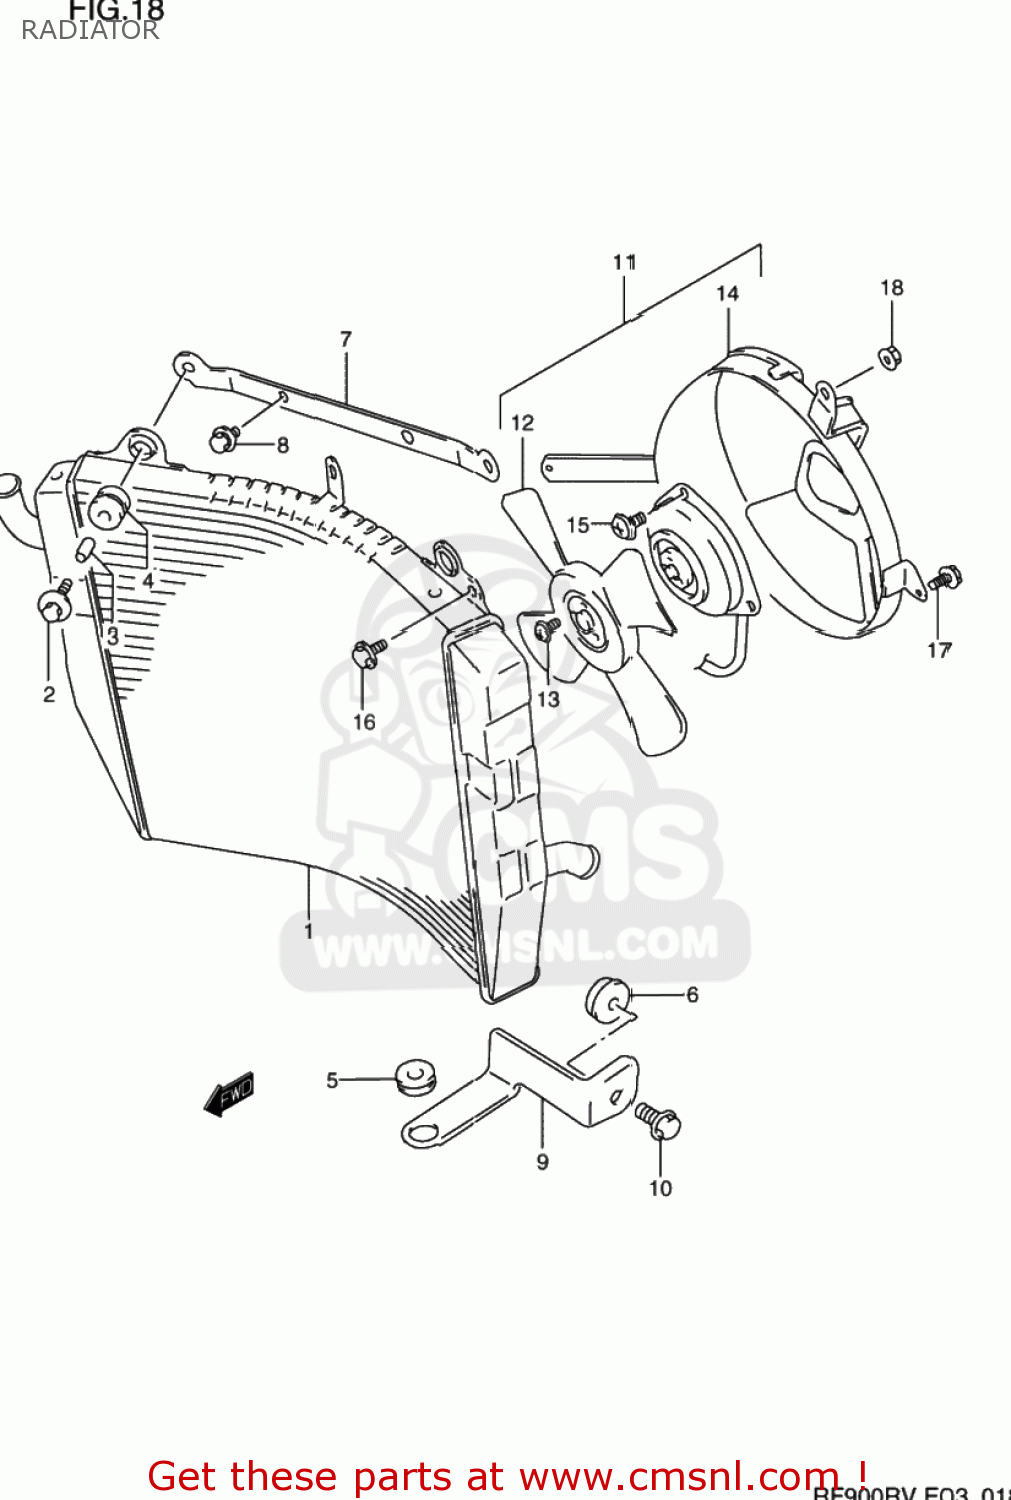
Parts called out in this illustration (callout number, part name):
1	RADIATOR ASSY,WATER
2	BOLT(6X25)
3	SPACER(6.5X10.5X12)
4	CUSHION,RADIATOR LWR
5	CUSHION
6	SPACER,RADIATOR BRACKET LWR
7	BRACKET COMP,RADIATOR
8	BOLT
9	BRACKET COMP,RADIATOR
10	BOLT
11	FAN ASSY,RADIATOR
12	FAN
13	SCREW 4X6
14	SHROUD ASSY,FAN
15	SCREW
16	BOLT
17	BOLT
18	NUT
